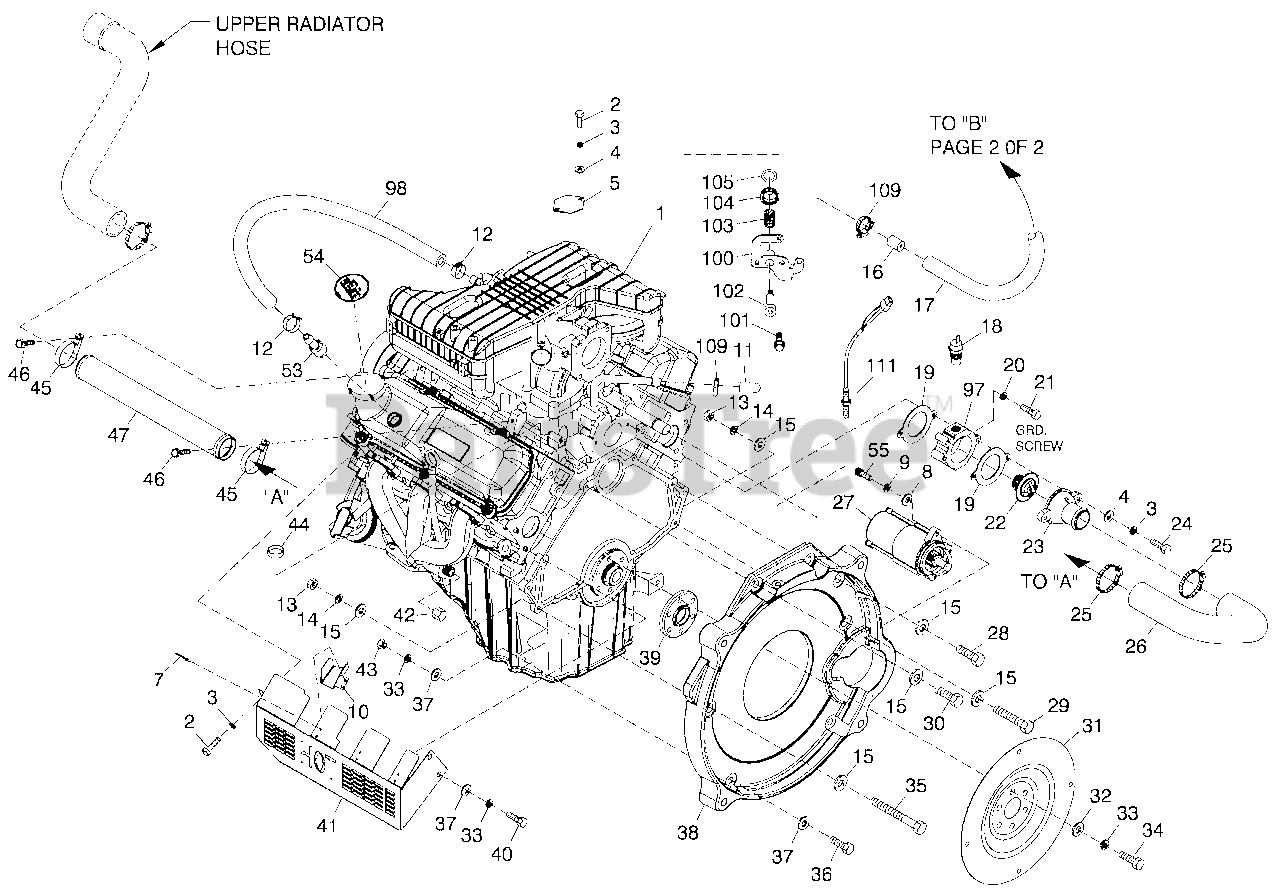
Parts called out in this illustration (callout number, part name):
1	ENGINE 4.2L G3 (FWD)
2	SCREW HHC M6-1.0 X 16 C8.8
3	WASHER LOCK M6-1/4
4	WASHER FLAT 1/4-M6 ZINC
5	COVER IAC ACTUATOR
6	SHIELD SPARK PLUG BOOT RH
7	RIVET POP .125 X .275 SS
8	WASHER FLAT 5/16-M8 ZINC
9	WASHER LOCK M8-5/16
10	SHIELD SPARK PLUG BOOT LH
11	CAP ANTIFREEZE 5/8"ID X 2.5"LG
12	CLAMP HOSE BAND 1.0"
13	NUT HEX M12-1.75 G8 YEL CHR
14	WASHER LOCK M12
15	WASHER FLAT M12
16	RESTRICTOR COOLANT BYPASS
17	HOSE COOLANT BYPASS 4.2L
18	SWITCH HI-TEMP 245D X 3/8NPT
19	GASKET THERMOSTAT 4.2L
20	WASHER LOCK M5
21	SCREW HHTT M5-0.8 X 10 BP
22	THERMOSTAT 192 DEGREE
23	THERMOSTAT HOUSING
24	SCREW HHC M6-1.0 X 60 C8.8
25	CLAMP HOSE #28 1.32-2.25
26	HOSE RADIATOR REAR
27	STARTER MOTOR 12V
28	SCREW HHC M12-1.75 X 30 C8.8
29	SCREW HHC M12-1.75 X 60 C10.9
30	SCREW HHC M12-1.75 X 40 C8.8
31	FLEX PLATE G3
32	WASHER FLAT .45 X 1.00
33	WASHER LOCK M10
34	SCREW HHC M10-1.0 X 30 C10.9
35	SCREW HHC M12-1.75 X 90 C10.9
36	SCREW HHC M10-1.5 X 35 C8.8
37	WASHER FLAT 3/8-M10 ZINC
38	ENGINE ADAPTER 4.2L MACHINED
39	SPACER FLEXPLATE 4.2L
40	SCREW HHC M10-1.5 X 20 C8.8
41	HEAT SHIELD EXH 4.2L LH
42	CAP TUBE M22-1.5 STEEL
43	NUT HEX M10-1.5 G8 YEL CHR
44	PLUG EXPANSION 14 OD
45	CLAMP VINYL 1.5 X .281 Z
46	SCREW HHC M6-1.0 X 25 LONG
47	TUBE UPPER COOLANT
48	SCREW HHC M5-0.8 X 20 G8.8
49	IGNITION COIL ASSY
50	SCREW HHC M5-0.8 X 12 C8.8
52	BRACKET IGNITION COILS G3 4.2L
53	VALVE PCV G3
54	DECAL REFER TO OWNERS MANUAL
55	SCREW SHC M8-1.25 X 30 G12.9
56	WELDMENT IDLER BRACKET 4.2L
57	PULLEY GROOVED ENGINE IDLER
58	BOLT HEX FL HD M8-1.25 X 28
59	CAP ANTIFREEZE RUBBER 8.5DIA
60	CLAMP HOSE BAND .75
61	STRAP INTAKE ACTUATOR
62	CAP ANTIFREEZE 5/8"ID X 1.2"LG
63	BRACKET DC ALTERNATOR LH 4.2L
64	ALTERNATOR DC W/OUT PULLEY
65	SPACER ALTERNATOR 4.2L G3
66	CLAMP HOSE BAND .50
67	CAP VINYL 3/8"ID X 1"DP BLK
68	SWITCH OIL PRESSURE 10PSI 2P
69	SCREW HHC M8-1.25 X 25 C8.8
70	SPACER DC ALTERNATOR PULLEY
71	PULLEY 117 OD DC ALTERNATOR
72	SCREW HHC M10-1.5 X 160 C8.8
73	SCREW HHC M8-1.25 X 115 LONG
74	SCREW HHC M8-1.25 X 105 LONG
75	TUBE COOLANT LOWER RADIATOR
76	O-RING 1-1/2" X 1-3/4" X 1/8"
77	PULLEY WATER PUMP 4.2L
78	SCREW HHC M6-1.0 X 12 G8.8
79	SPACER 46.5 O.D. X 15 I.D. X 5 THK.
80	SCREW HHC M14-1.5 X 40 LONG GRADE 10.9
81	BELT SERPENTINE 71.04"
82	HARMONIC BALANCER REWORK 4.2L
83	WASHER FLAT M5
84	SCREW HHC M5-0.8 X 10 C8.8
85	BRACKET DC ALTERNATOR RH 4.2L
86	WASHER NYLON .50 X .87 X .06
87	ADAPTER M12-1.75 X 3/8NPT
88	BARBED STR 3/8NPT X 3/8
89	CLAMP HOSE .38-.87
90	HOSE OIL DRAIN ASSY 21"
91	SCREW HHC M6-1.0 X 12 SS
92	WASHER LOCK 1/4-M6 SS
93	WASHER FLAT 1/4 SS
94	HEAT SHIELD EXH 4.2L RH
95	CAP VINYL .5"ID X 1.0"DP BLK
96	CLAMP HOSE BAND .63
97	ADAPTER THERMOSTAT
98	HOSE COOL 5/8"ID 250#WP (24"LG)
99	BSHG RDCR HEX 1/4 TO 1/8
100	TUBE ASSY EGR OUTLET REWORK
101	SCREW HHC M6-1.0 X 15 LONG
102	BOLT STRIP 3/8-16 X 1-1/4
103	SPRING COMPRESSION .711 X 1.00
104	PRESSURE RELIEF VALVE
105	O-RING 29mm I.D. X 36mm O.D. X 3.5mm
106	SPARK PLUG WIRE SET 4.2L
107	RETAINER SPARK PLUG WIRE - LOOSE TYPE
108	RETAINER SPARK PLUG WIRE - ATTACHED TYPE
109	CLAMP HOSE #10 .56-1.06
110	HARN LOW OIL PRESSURE SWITCH
111	ASSY MAGPICKUP(3/8-24 MALE)
114	OIL FILTER 1.6,2.5,3.0,4.2L G3
